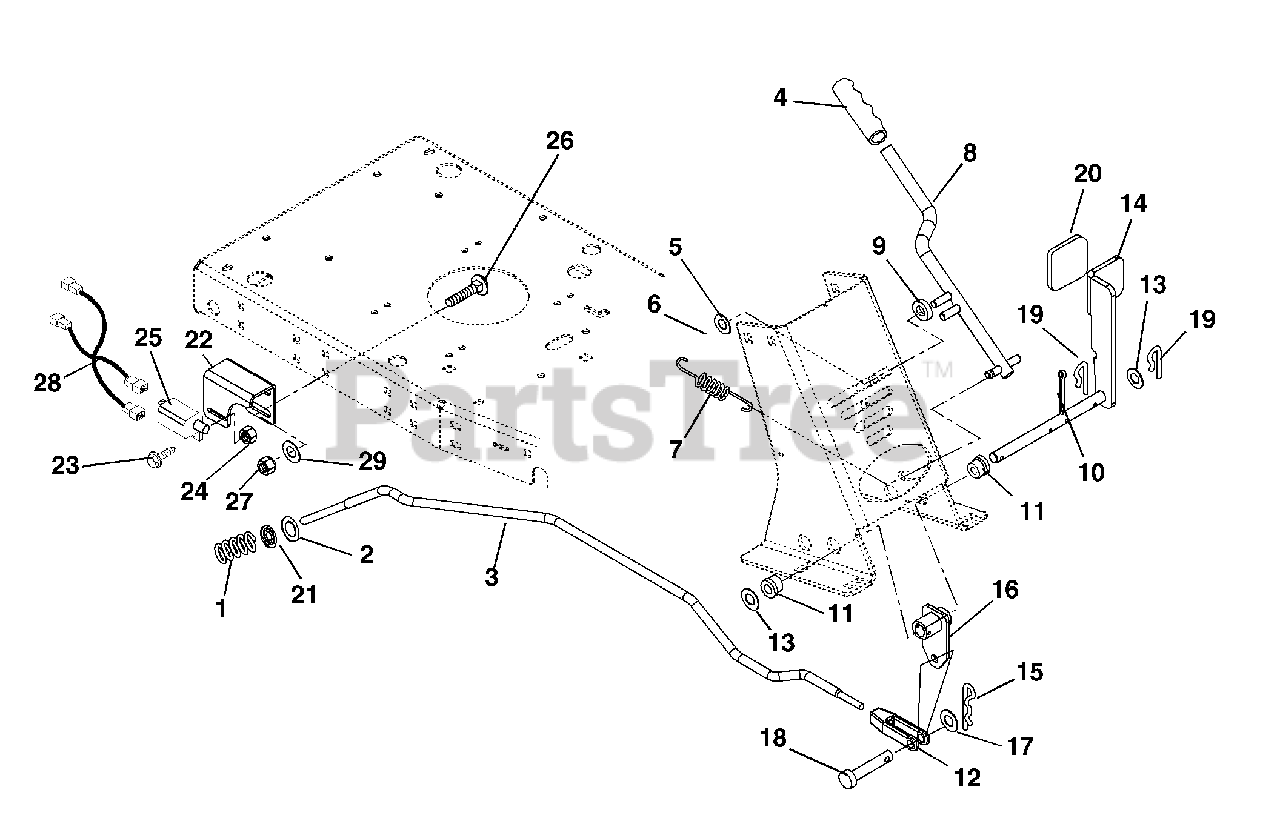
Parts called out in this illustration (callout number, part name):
1	Spring, Compression .080 x .52 x 2.90
2	Washer, Flat Steel .33 x 2.125 x .098
3	Rod, Brake
5	Washer, Flat Steel .38 x .875 x .083
6	Nut, Locking Top Flange .38-16
7	Spring, Tension .048 x .44 x 2.12
8	Weldment, Parking Brake
9	Bushing, Flange .406 x .88 x .27 x .140 Grade 2
10	Pin, Cotter .12 x 1.00 Extended Prong Square Cut
11	Bushing, Flange .515 x .75 x .745 x 1.00 Nylon
12	Yoke, .312-24 x 2.25
13	Washer, Flat Steel .505 x 1.00 x .062
14	Weldment, Brake Pedal
15	Pin, Hair
16	Brake Rod Arm and Hub
17	Washer, Flat Steel .38 x .87 x .179
18	Pin, Clevis .312 x .822
19	Clip, Spring
20	Grip, Pedal
21	Nut-Push .312
22	Bracket, Switch Mount
23	Screw, Machine 10-24 x .75 Hex Washer Head
24	Nut, Locking Nylon 10-24 with Insert
25	Switch, Single Pole (N.O.)
26	Bolt, Round Head Square Neck .38-16 x 1.00 Grade 5
27	Nut, Locking Nylon .38-16
28	Jumper, Harness
29	Washer, Flat Steel .406 x .812 x .065
